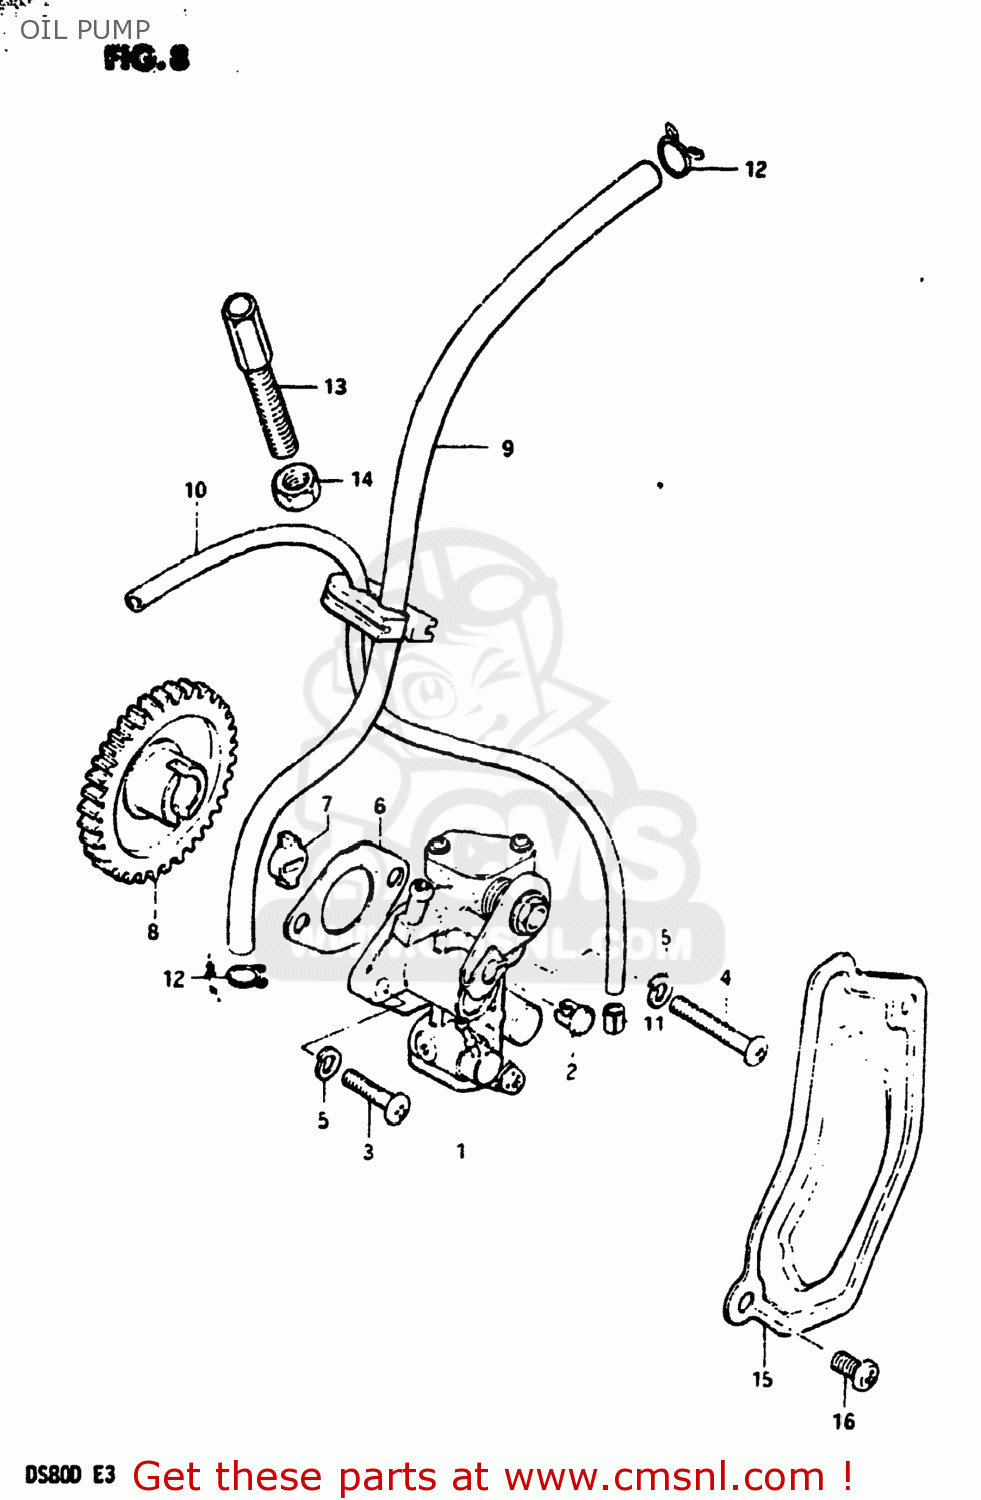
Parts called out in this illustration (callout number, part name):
1	PUMP ASSY,OIL
2	TERMINAL,CABLE
3	SCREW
4	SCREW
5	LOCK WASHER
6	GASKET,OIL PUMP (NAS)
7	PIECE,OIL PUMP DRIVE
8	GEAR,OIL PUMP DRIVE
9	HOSE
10	HOSE,NO.2
11	CLIP
12	CLIP
13	BOLT
14	NUT
15	CRANKCASE SET
16	SCREW
